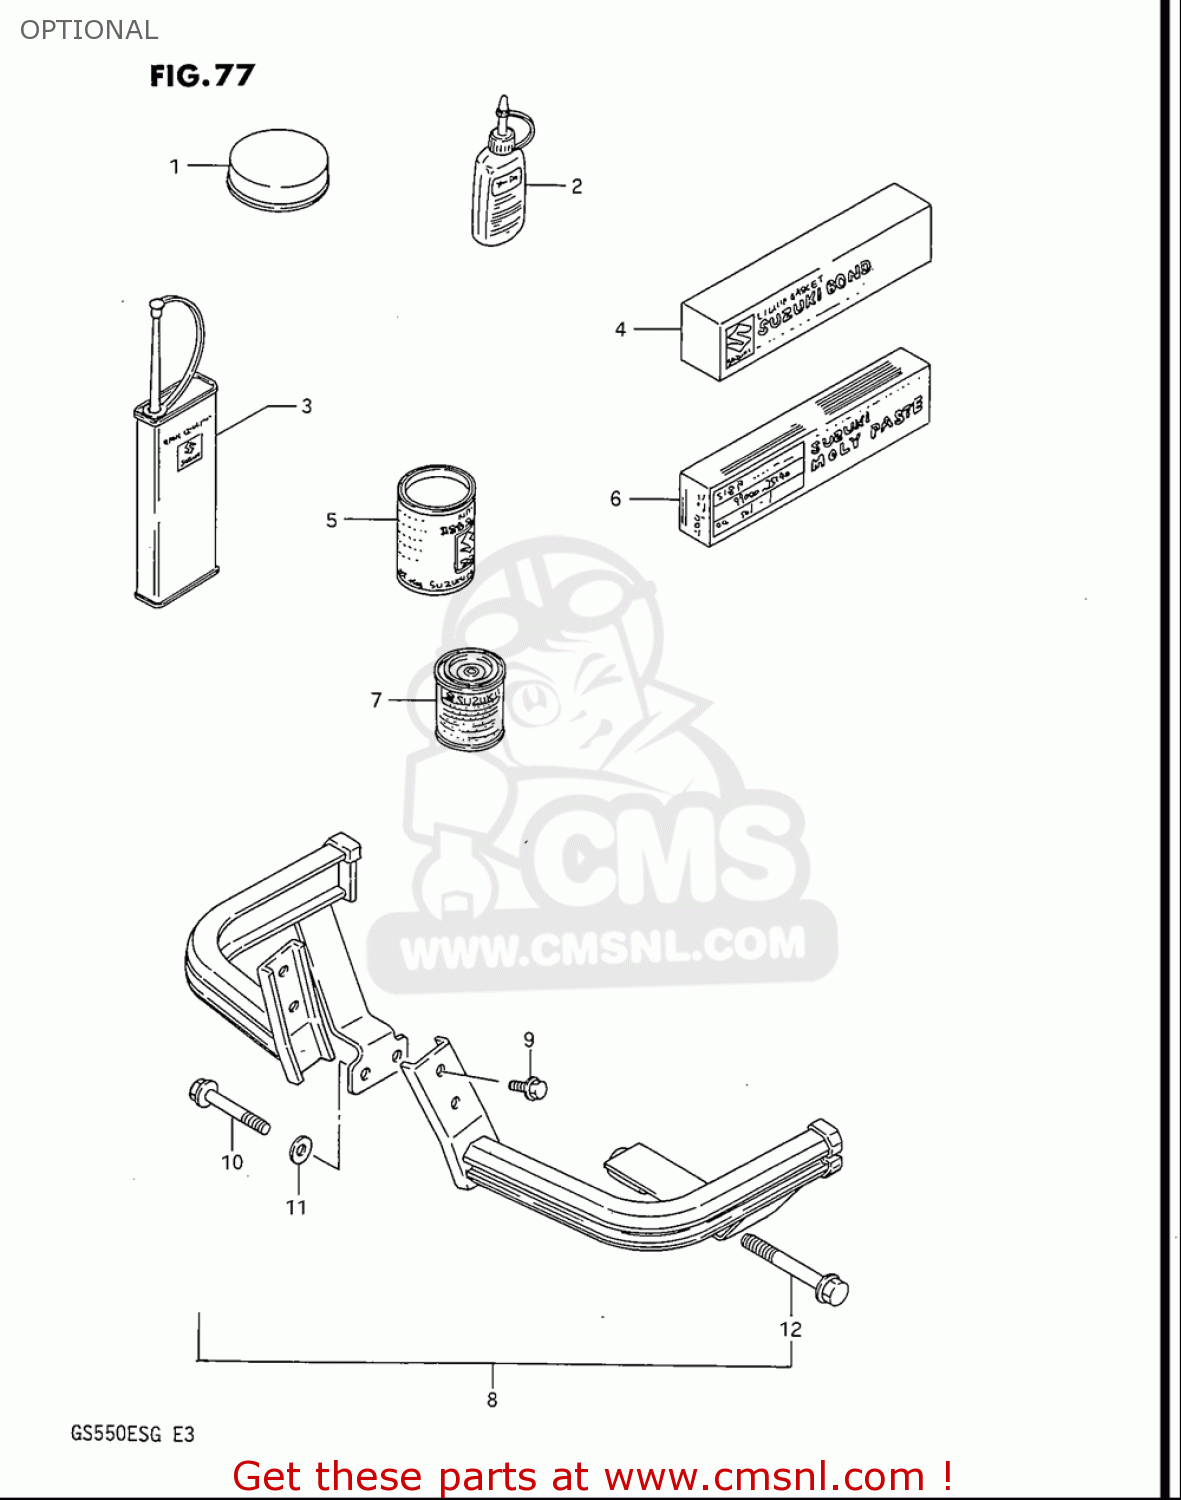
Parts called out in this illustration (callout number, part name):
1	GREASE,PBC FOR BRK PAD 20G
2	THREAD LOCK NO.1342
3	THREAD LOCK NO.1401 CLEAR 200G
4	LIQUID GSKT NO.1207B 100G BLK
5	GREASE(C)EP2 LITHIUM 150G
6	SUZUKI MOLY PASTE
9	BOLT
10	BOLT
11	WASHER (8.5X24X2.3)
